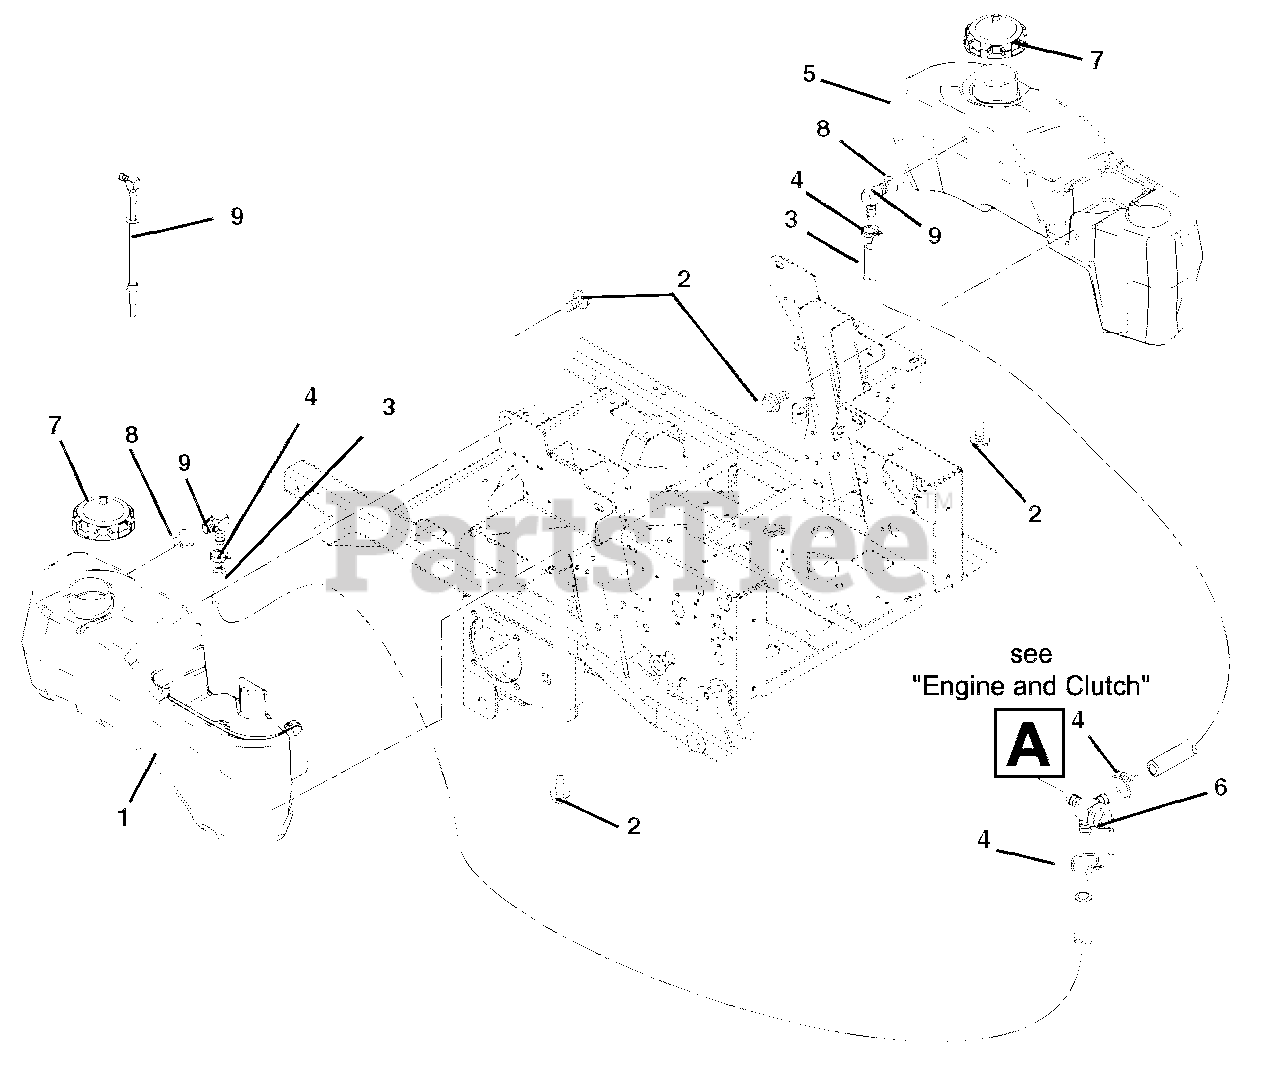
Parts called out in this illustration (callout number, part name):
1	Tank, Right Hand Fuel
2	Bolt, SEMS .31-18 x .62
3	Hose, .25 Low-PERM Bulk Gas (2@42in.)
4	Clamp, Fuel Line
5	Tank, Left Hand Fuel
6	Valve, Fuel
7	Cap, Fuel
9	Assembly, Large Tank Fuel Pick-up
